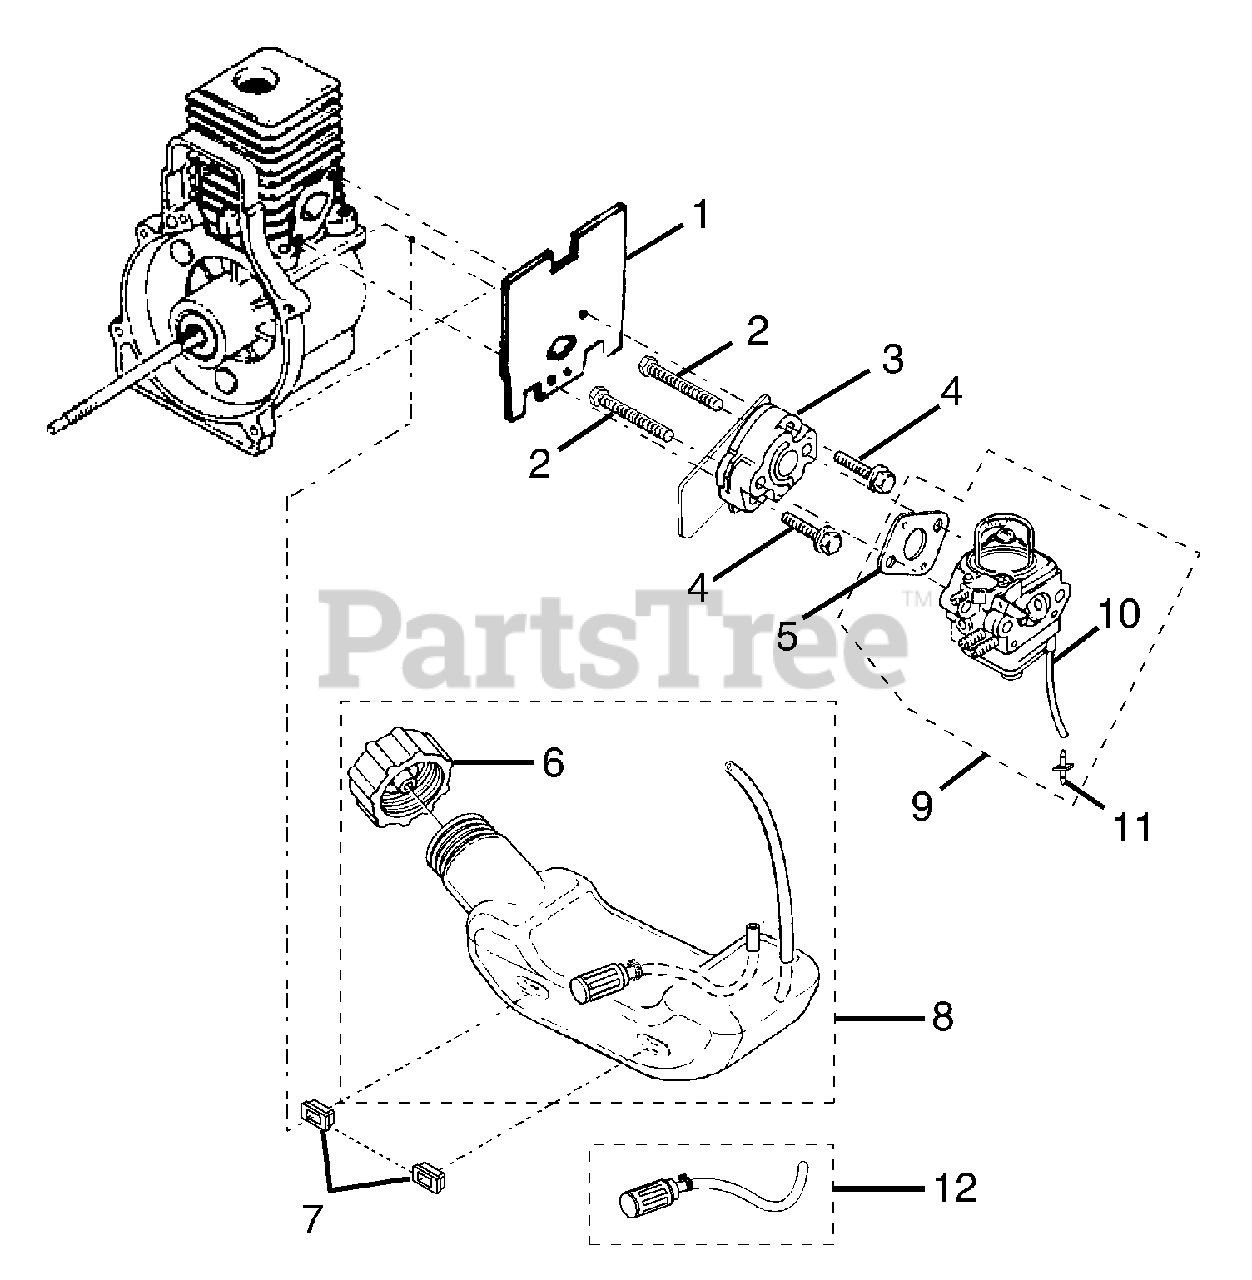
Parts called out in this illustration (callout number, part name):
1	HEAT DAM GASKET
2	CARBURETOR BOLT
3	HEAT DAM
4	PAN HEAD SEMS SCREW
5	CARBURETOR GASKET
6	FUEL CAP
8	FUEL TANK ASSEMBLY
9	CARBURETOR ASSEMBLY KIT
10	RUBBER HOSE (635 mm)
11	INLINE FUEL FITTING
12	FUEL FILTER KIT
